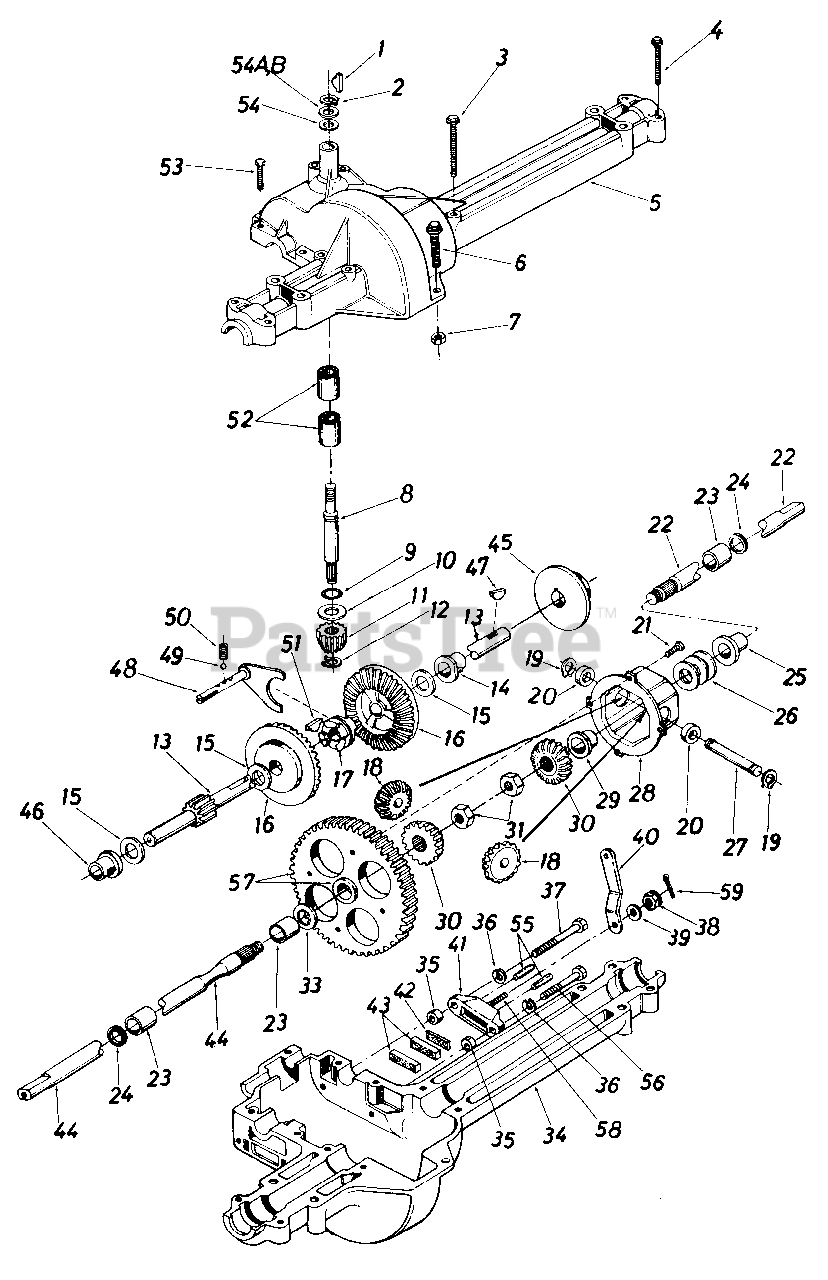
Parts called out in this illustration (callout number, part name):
1	#4 Hi-Pro Key 3/32 x 518" Dia.
2	Snap Ring .625" Shaft
3	Hex Bolt 1/4-20 X 1.75" Lg.
4	Hex Bolt 1/4-20 x 1.25" Lg.
5	Upper Housing
6	Hex Fl-Bolt 1/4-20 X .75" Lg.
7	Hex Nut 1/4-20 Thd.
8	Input Shaft
9	Square Seal 518" I.D.
10	Thrust Washer 518" I.D. x 1.25" O.D.
11	Pinion Input 14T
12	Retaining Ring 7/16" Ext.
13	Drive Shaft R.H.
14	Flange Brg. 5/8" I.D. x 3/4" Lg.
15	Fl-Wash.
16	Bevel Gear 42T
17	Clutch Collar
18	Miter Gear 15T
19	Snap Ring
20	Thrust Bearing 1/2" I.D. x 1.0" O.D.
21	Pan Head Scr. 1/4-20 X .50" Lg. w/Patch
22	Axle R.H.
23	Sleeve Bearing 3/4" I.D. x 1.0" Lg.
24	Oil Seal 3/4" I.D.
25	Flange Bearing 3/4" I.D. x 15/16" Lg.
26	Fl-Wash. 760" I.D. x l.49" O.D.
27	Cross Shaft
28	Differential Housing Ass'y.
30	Miter Gear
31	Hex Ins. L-Nut 1/2-20 Thd.
33	Fl-Wash. .75" I.D. x 1.5" O.D.
34	Lower Housing
35	Spacer .53" O.D. x 3/8" Lg.
36	L-Wash. 1/4" I.D.
37	Hex Bolt 1/4-20 x 1.50" Lg. (Grade 5)
38	Castle Nut 5/16-24 Thd.
39	Fl-Wash. .34" I.D. x .875" O.D.
40	Actuating Arm- -R.H.
41	Brake Yoke
42	Puck Plate
43	Brake Puck
44	Axle L.H.
45	Brake Disc
46	Flange Bearing 518" I.D. x 15/16" Lg.
47	Woodruff Key 3/16 x 5/8 HT
48	Shift Fork Ass'y.
49	Ball Detent.250" Dia.
50	Spring Detent
51	#9 Hi-Pro Key 3116" x 3/4" Dia. HT
52	Needle Brg. 518" I.D. x 1/2" Lg.
53	Hex Bolt 1/4-20 x 1.00" Lg.
54	Fl-Wash. 5/8" I.D. x .030
54A	Fl-Wash. 518" I.D. x .040
54B	Fl-Wash. 518" I.D. x .020
55	Actuating Pin 5/16" Dia.
56	Hex Bolt 1/4-20 x 1.50" Lg. (Grade 5)
57	Differential Gear 72T Ass'y. w/Bearing
58	Sq. Hd. Bolt 5/16-24 Thd.
59	Cotter Pin 3/32" Dia. x .50" Lg.
